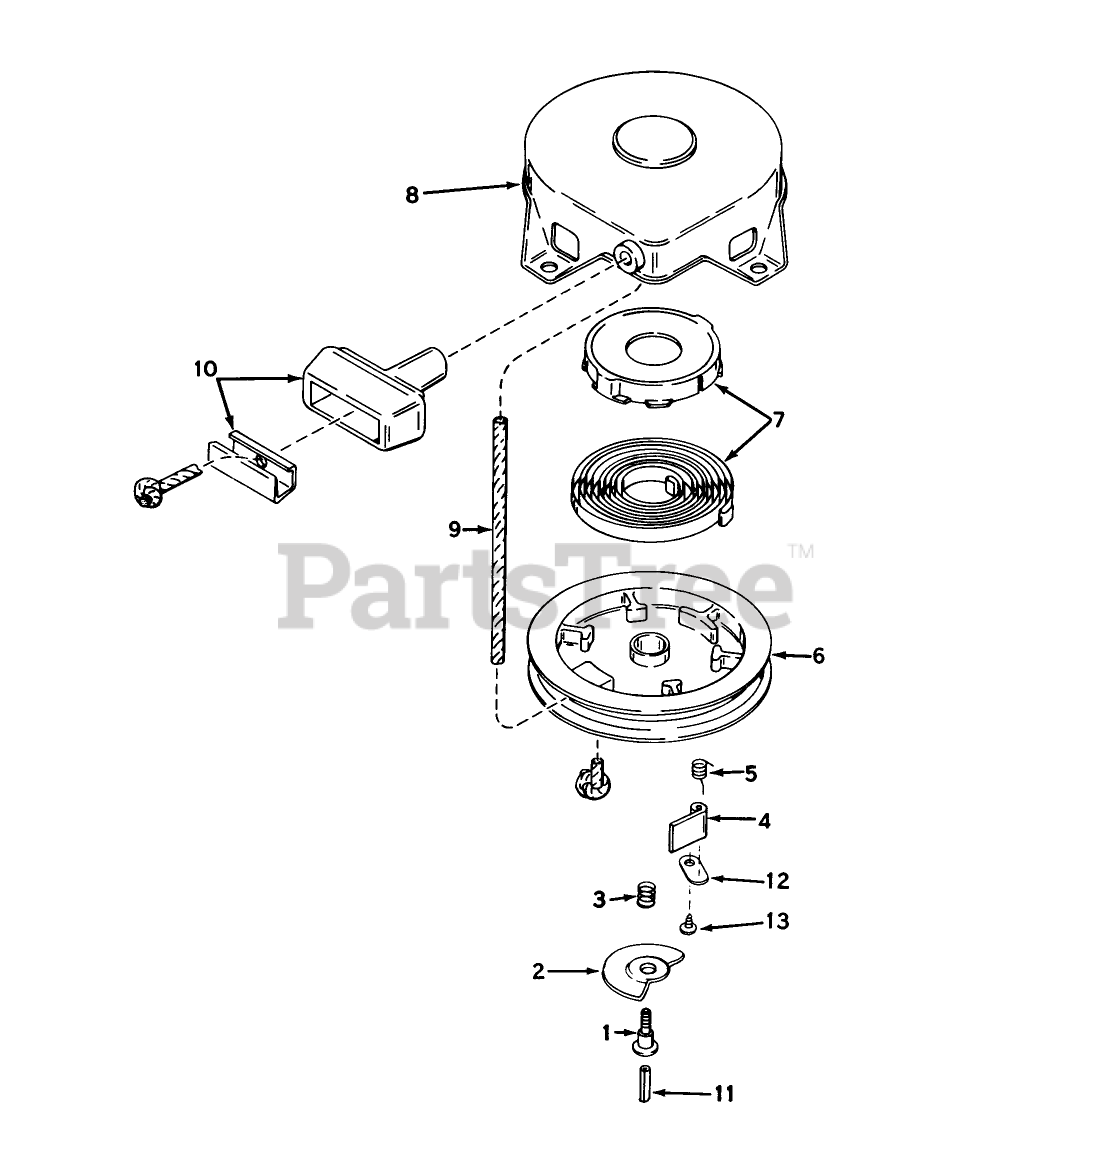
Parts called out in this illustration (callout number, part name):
1	Screw
2	Cam-Dog
3	Spring-Brake
4	Dog-Starter
5	Spring-Dog
6	Pulley
7	Spring Keeper Assy
8	STARTER HOUSING ASSY
9	Rope-Starter
10	Assy., Starter
11	Centering
12	Retainer-Dog
13	Screw
